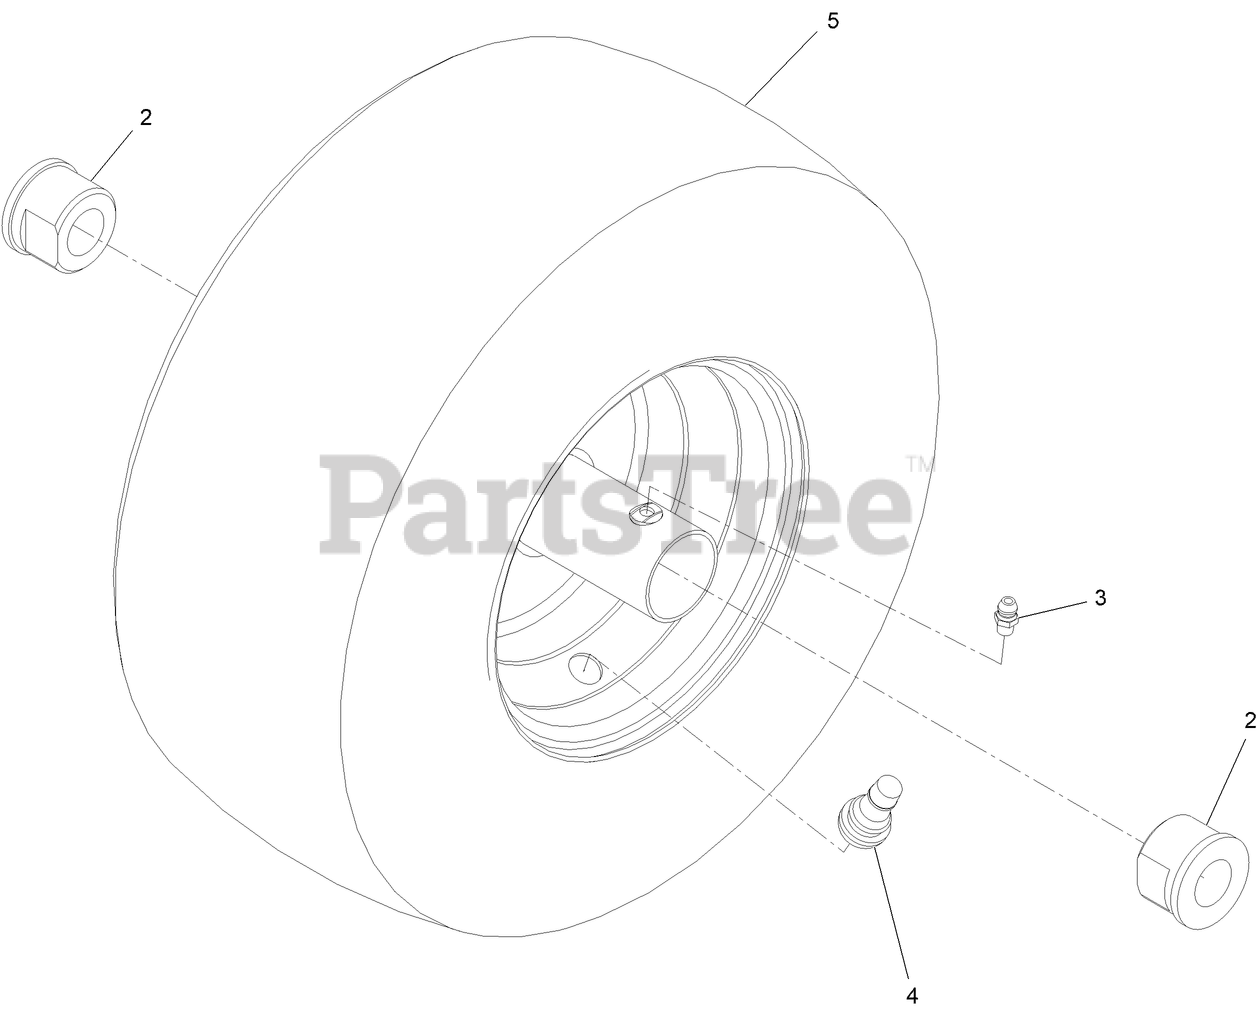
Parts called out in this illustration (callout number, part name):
2	BUSHING-FLANGE
3	Zerk 1/4-28 Str Thrd Forming
4	VALVE
